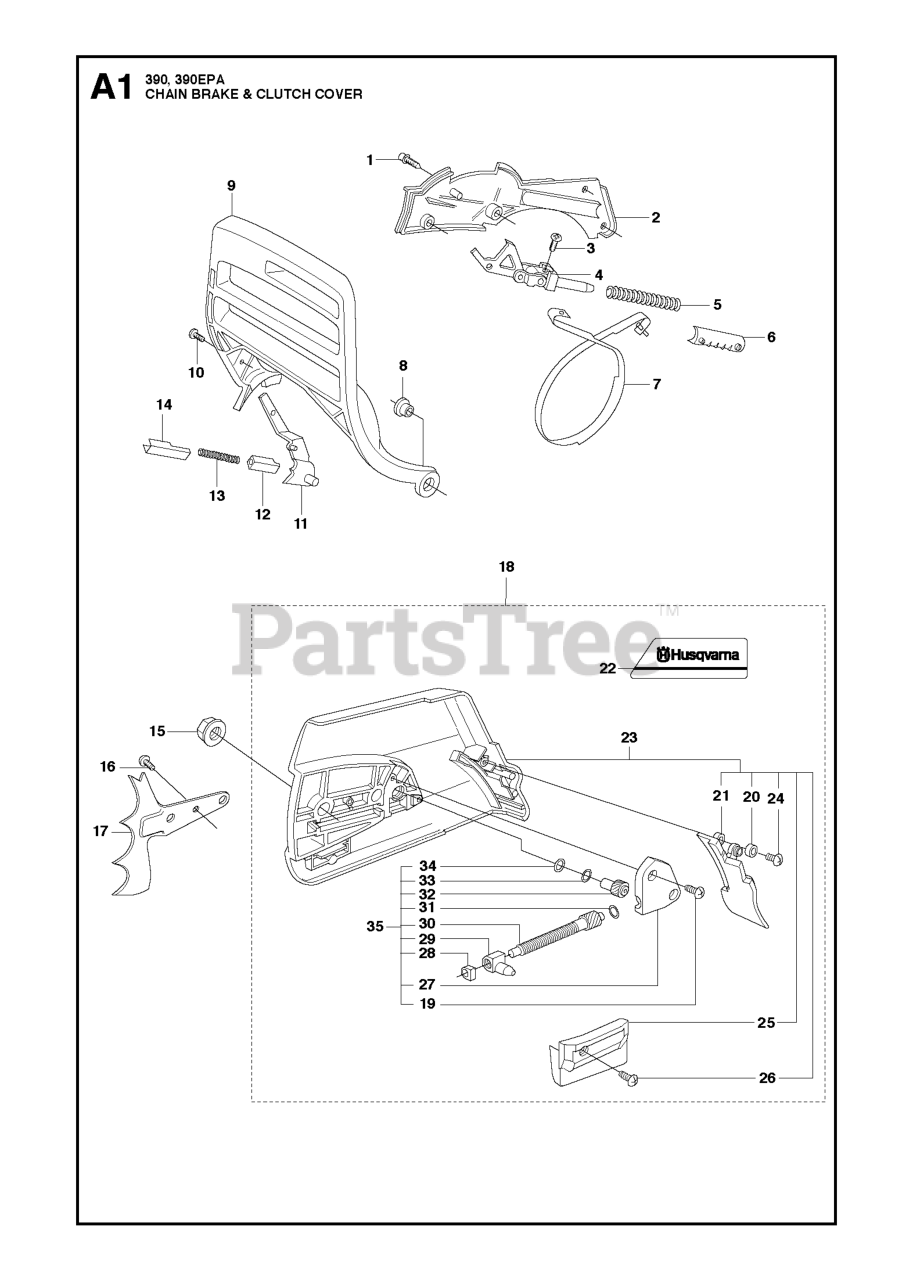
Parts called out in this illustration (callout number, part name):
1	SCREW
4	KNEE JOINT
5	BRAKE SPRING
6	%SUPPORT
7	BRAKE BAND
9	HAND GUARD
10	SCREW IHSCM M4X12 12.9 TBO
11	BRAKE LEVER
13	LOCK SPRING
15	NUT M8 FLANGE
17	SPIKE OUTER
18	CHAIN BRAKE COVER
23	CLUTCH COVER
25	CHAIN GUIDE
30	WORM SCREW / ADJUSTER
32	WORM WHEEL
35	KIT-CHAIN TENSIONER
